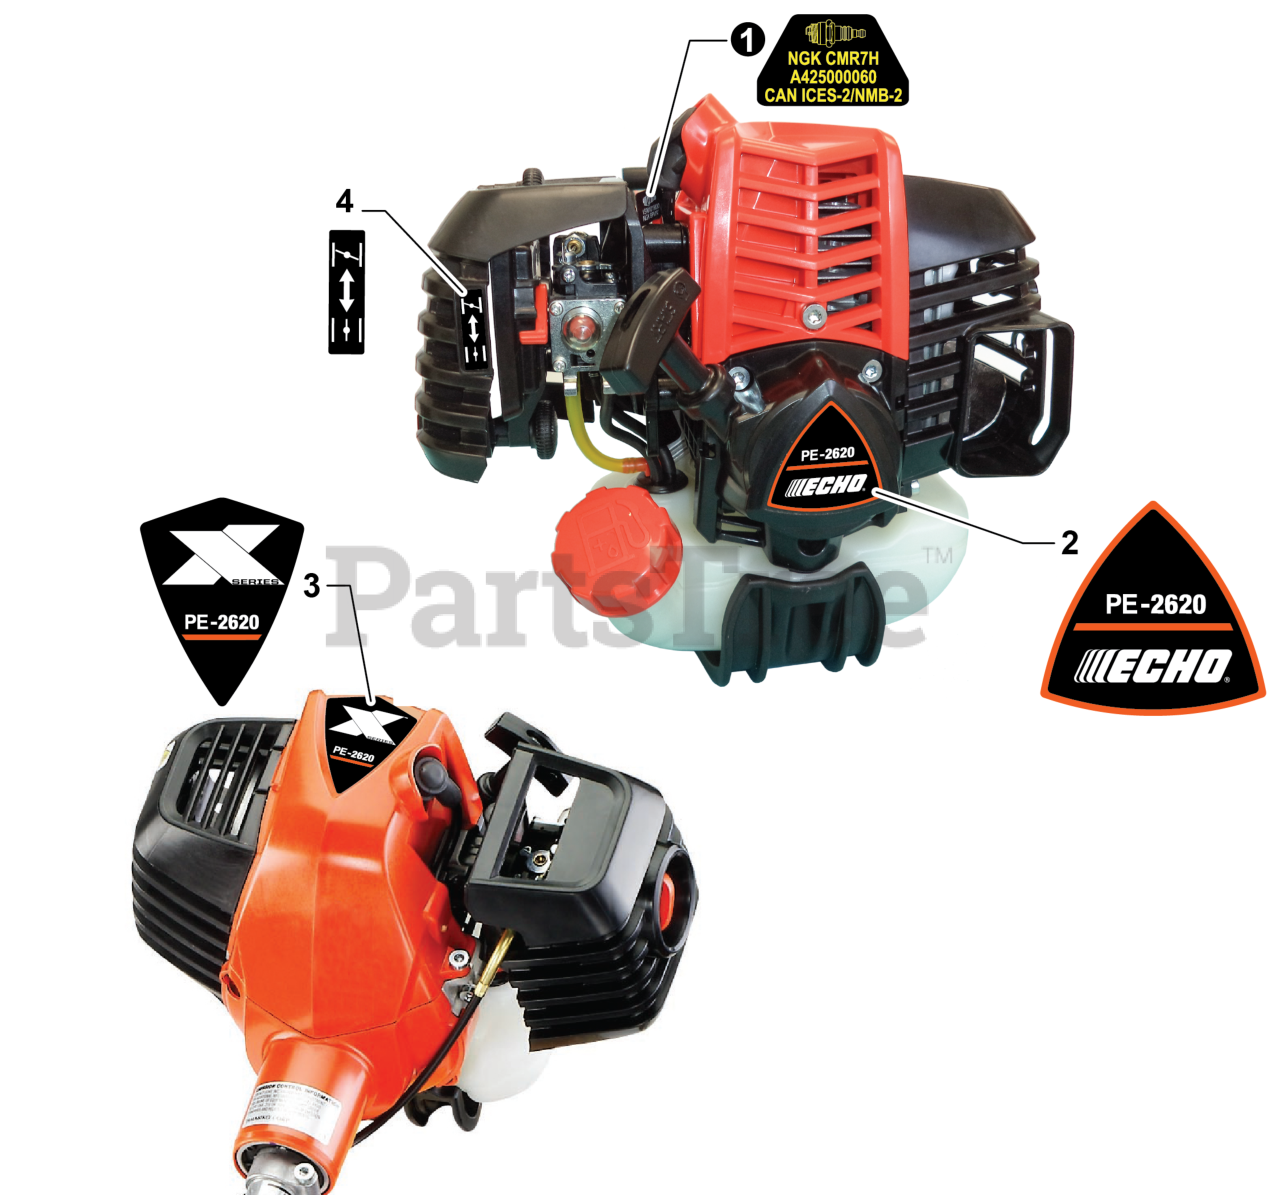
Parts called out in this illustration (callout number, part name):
1	LABEL - SPARK PLUG - CMR7H
2	LABEL - RECOIL STARTER
3	LABEL - MODEL PE-2620
4	LABEL - CHOKE
